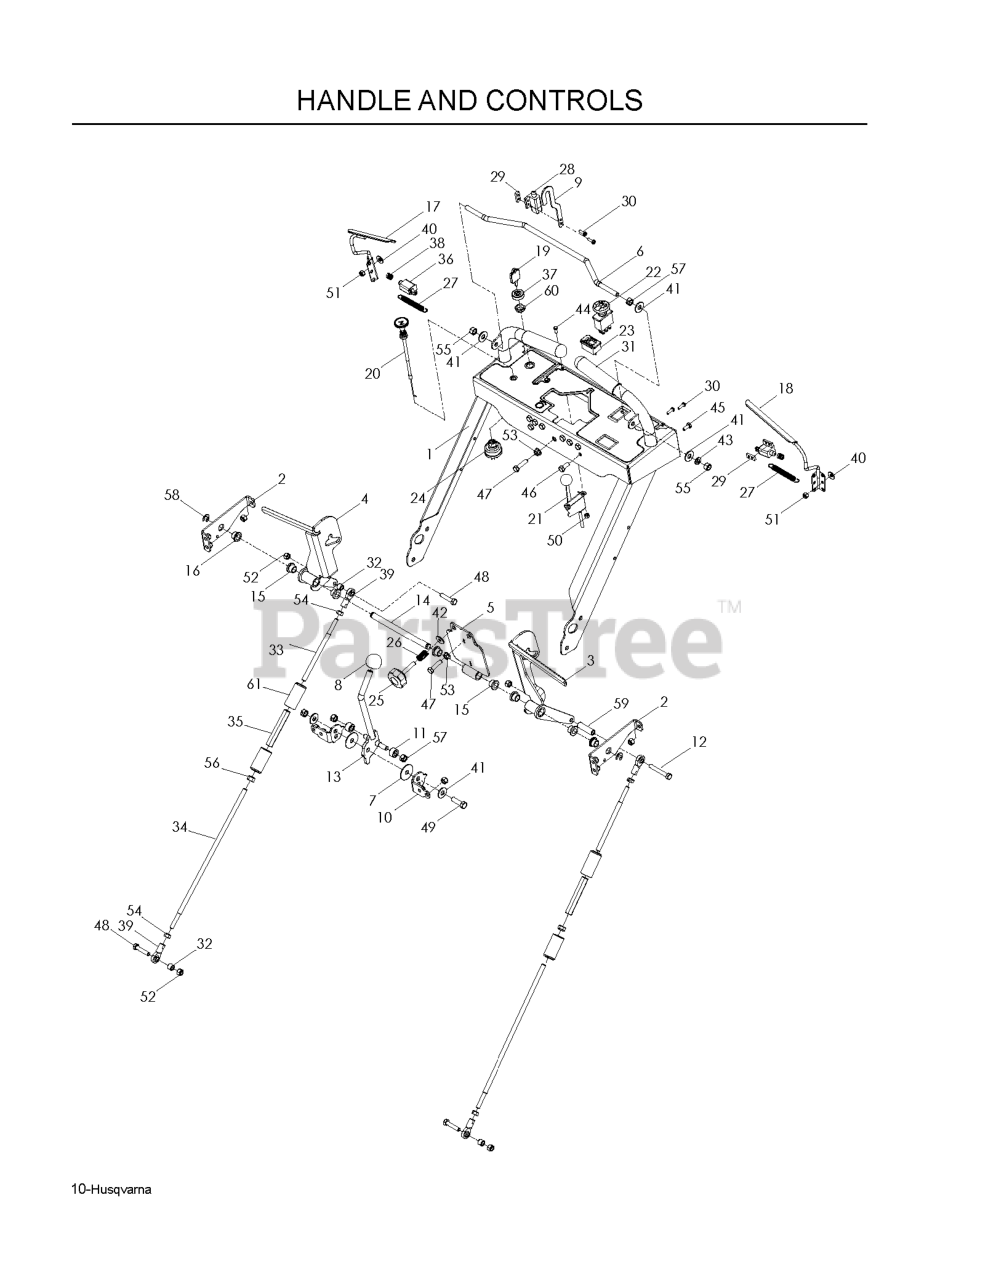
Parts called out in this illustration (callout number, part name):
1	HANDLE W/DECALS
3	DRIVE LEVER LT
4	DRIVE LEVER RT
5	TRACKING PLATE
7	WASHER, FRICTION
9	NEUTRAL ARM
10	FRICTION PLATE
12	HCS 5/16C X 2-3/4
13	GROUND SPEED LEVER
14	CROSS SHAFT
15	BUSHING, FLANGED NYLON
16	FLANGE BUSHING
19	KEY-PADDED
20	CHOKE CONTROL, COMPLETE
21	THROTTLE CONTROL W/BALL KNOB
22	RP.SWITCH, BLADE
23	HOUR METER
24	IGNITION SWITCH KIT
25	ADJUSTMENT KNOB
28	SWITCH, INTERLOCK
29	TAPPED PLATE
30	SCREW #10-24 X 5/8
33	SHORT LINKAGE
34	LINKAGE, LOWER
35	TURNBUCKLE, 3/8
37	CAP IGNITION NUT
38	SPRING, SWITCH
39	BALL JOINT, RIGHT HANDED
40	WASHER 1/4 FLAT
41	WASHER 3/8 FLAT
42	WASHER 5/16 FLAT
43	SLW 3/8 STD
44	HCS #10-24 X 1/2
45	HCS 1/4C X 5/8
46	HCS 5/16C X 3/4
47	BOLT, TAP 5/16-18
48	CAPSCREW 5/16 X 1/1/2 HEX HEAD
49	HCS 3/8C X 1 1/4 GR5
50	NUT 10-24 NYLOC
51	NUT.1/4-20.HEX.NYLOC.ZD
52	NUT 5/16 NYLOC
53	NUT 5/16C WHIZ
55	NUT 3/8-16 NYLOC
57	NUT 3/8C CENTERBLOCK
58	E-RING 1/2 (2 2)
60	DNO IGNITION NUT
